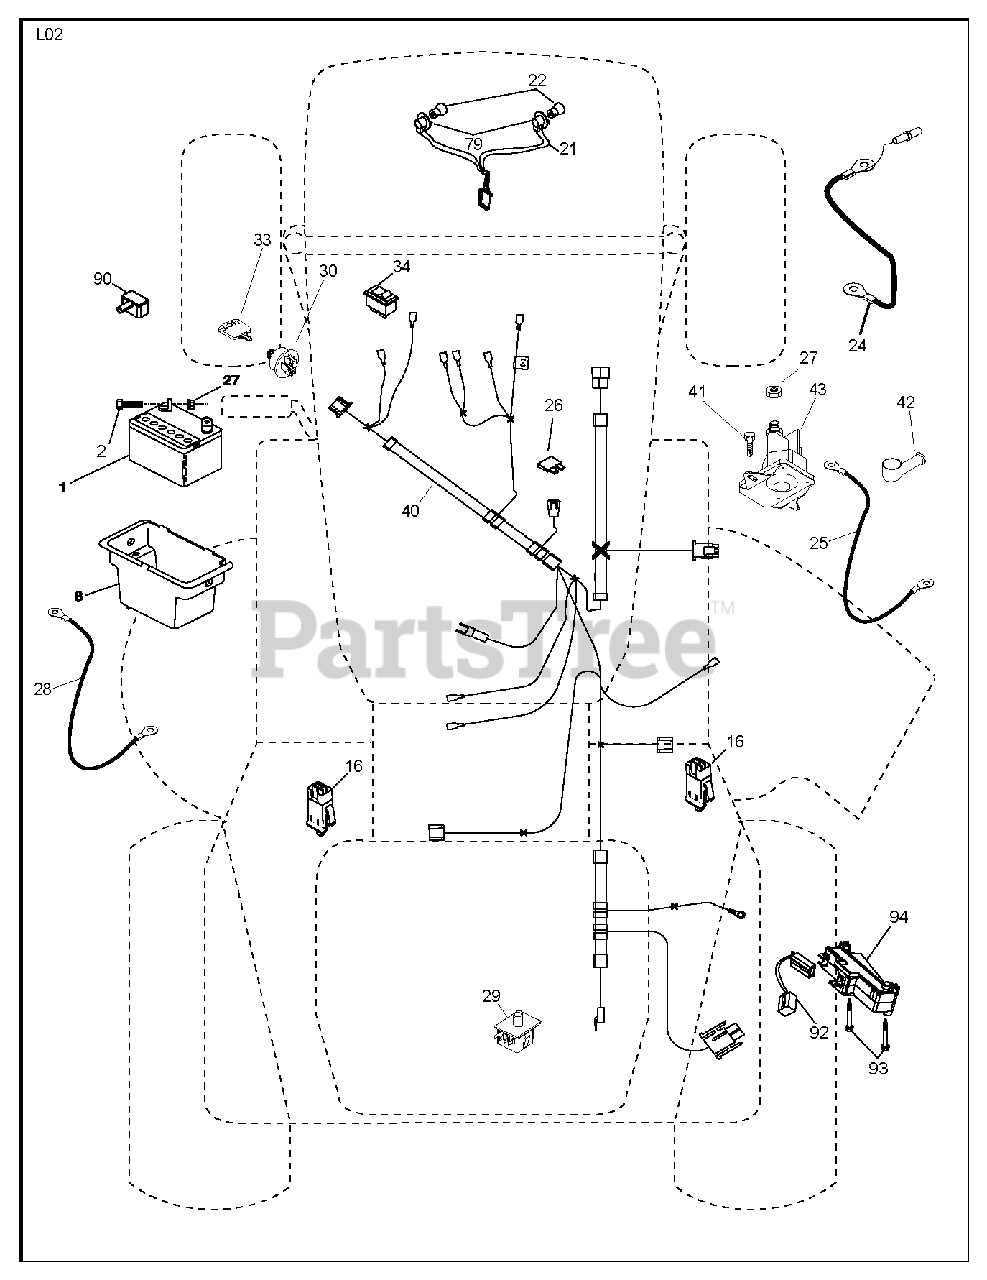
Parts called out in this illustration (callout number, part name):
1	REPL BY 532 12 38-99
2	BOLT.HEX.1/4.X.3/4.DICHROMATE
8	BOX.BATTERY.FENDER
16	SWITCH INTERLOOK PUSH-IN
21	HARNESS.W/LIGHT SOCKET
22	LIGHTBULB
24	CABLE.GROUND.REAR.BTRY.8GA.44"
25	CABLE.STARTER.6GA.11"RED
26	FUSE 20AMP
27	NUT
28	CABLE GROUND 6 GA. 12" BLACK
29	SWITCH.SEAT.DP W/RAMPS
30	SWITCH.IGN.DELTA.W.LGH.ROS
33	KEY.CHAIN.BLISTER.PACK.GEN.INT
34	SWITCH LT
40	HARNESS.IGN.CABLE.REG.
41	BOLT
42	TERMINAL COVER
43	SOLENOID.W/BRASS.PLUNGER
79	BULB HOLDER ASM.
90	COVER.TERMINAL.BATTERY
92	HARNESS.PIGTAIL.CONSLE
93	SCREW.PLASTITE
94	MODULE.REVERSE.ROS
